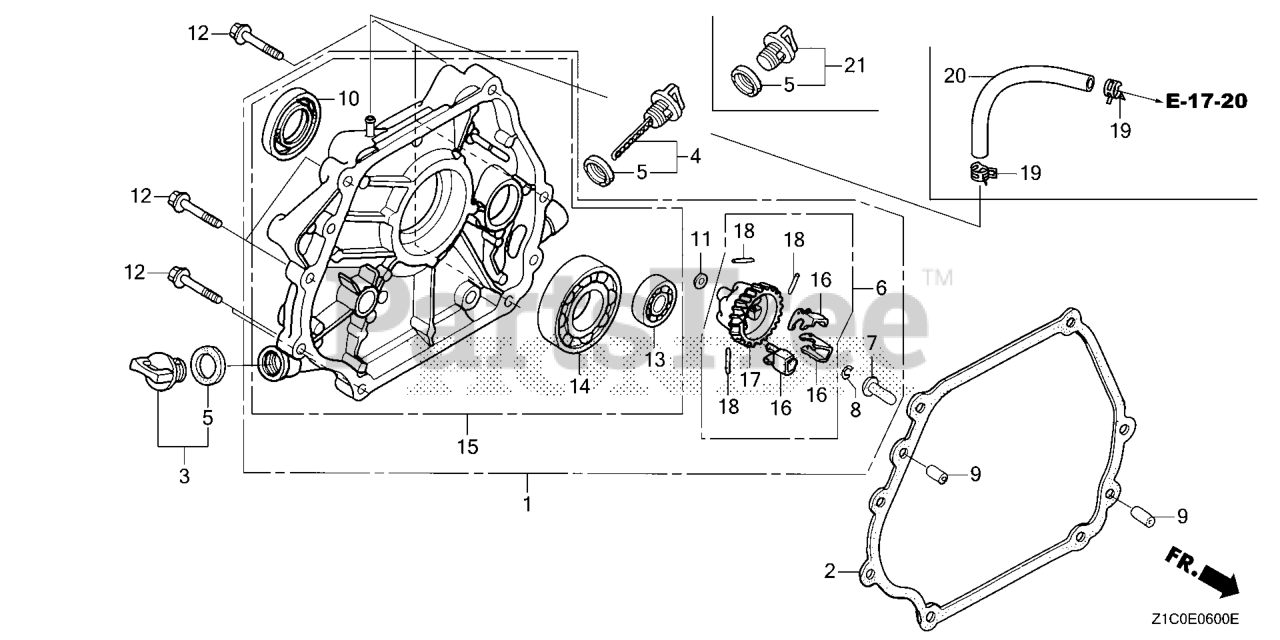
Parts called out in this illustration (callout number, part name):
1	COVER ASSY., CRANKCASE
2	GASKET, CRANKCASE COVER
3	CAP ASSY., OIL FILLER
4	CAP ASSY., OIL FILLER
5	GASKET, OIL FILLER CAP
6	GOVERNOR ASSY.
7	SLIDER, GOVERNOR
8	CLIP, GOVERNOR HOLDER
9	PIN, DOWEL (8X12)
10	OIL SEAL (35X52X8) (NOK)
11	WASHER, PLAIN (6MM)
12	BOLT, FLANGE (8X40) Use up to Engine SN 1003236.
13	BEARING, RADIAL BALL (6202)
14	BEARING, RADIAL BALL (6207)
16	WEIGHT, GOVERNOR
17	HOLDER, GOVERNOR WEIGHT
18	PIN, GOVERNOR WEIGHT
